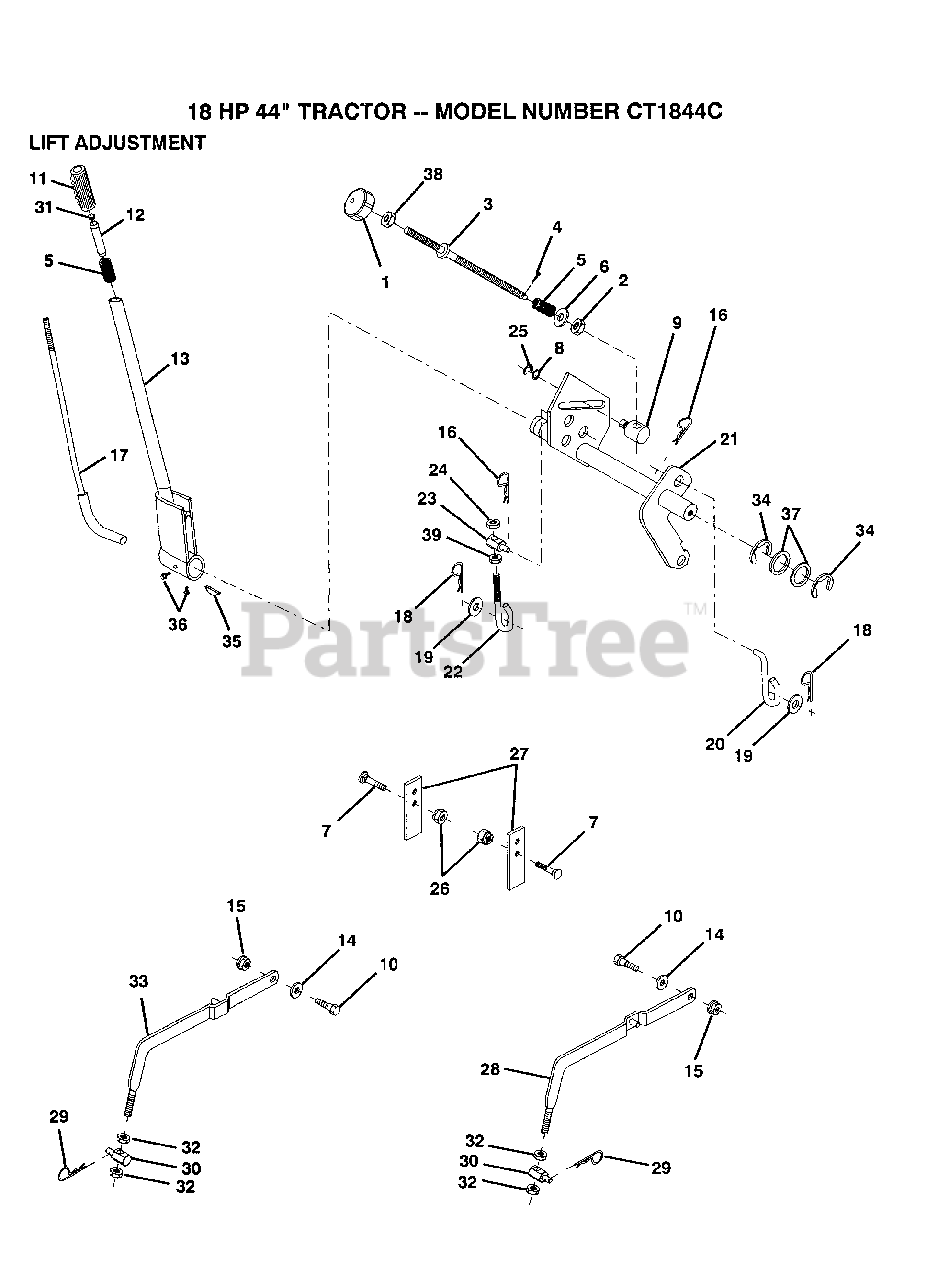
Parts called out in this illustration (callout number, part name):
2	NUT T
3	ROD LIFT LT
5	SPRING T
6	WASHER
8	WASHER
9	TRUNION LT
10	"BOLT, SHOULDER LT"
11	GRIP
14	WASHER T
15	NUT SPECIAL T
17	ROD ASS'Y LEVER
18	SPRING.RETAINER
20	LIFT LINK LT
22	PIVOT PIN T
25	KLIP RING
27	UPSTOP
28	RH SUSP ARM ASM
29	SPRING H
32	NUT
33	LH SUSP ARM ASM
34	E-RING
37	WASHER
38	NUT
39	NUT
